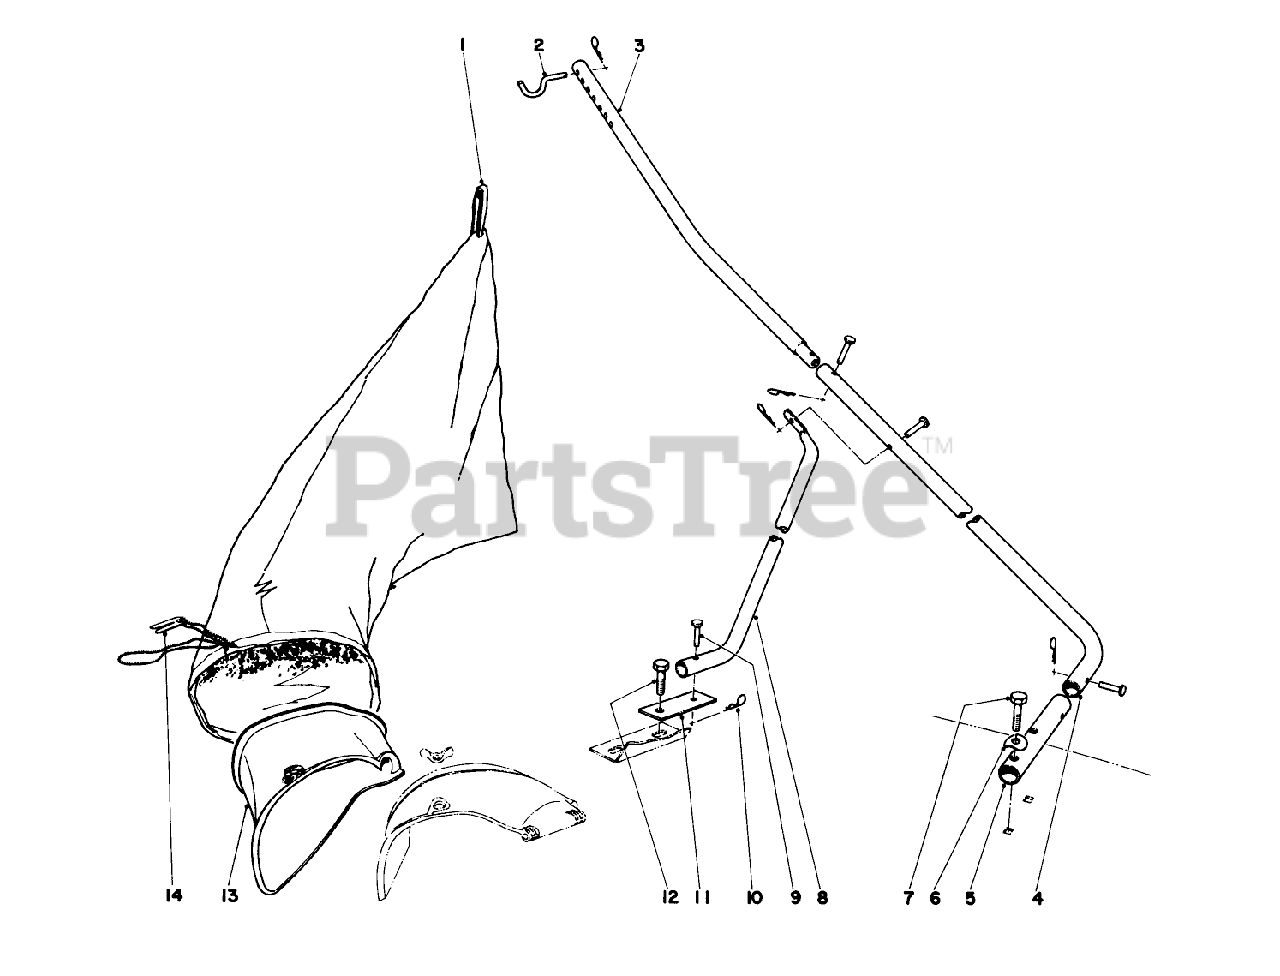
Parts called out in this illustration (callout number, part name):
1	Giant Bag
3	Long Bag Arm
5	Socket-Bag Arm
6	Curved Washer
7	SCREW-HH
8	Brace
10	PIN-COTTER, HAIR
11	Brace Support
12	SCREW-HH
13	Bag Chute
14	BAG CORD FASTENER
